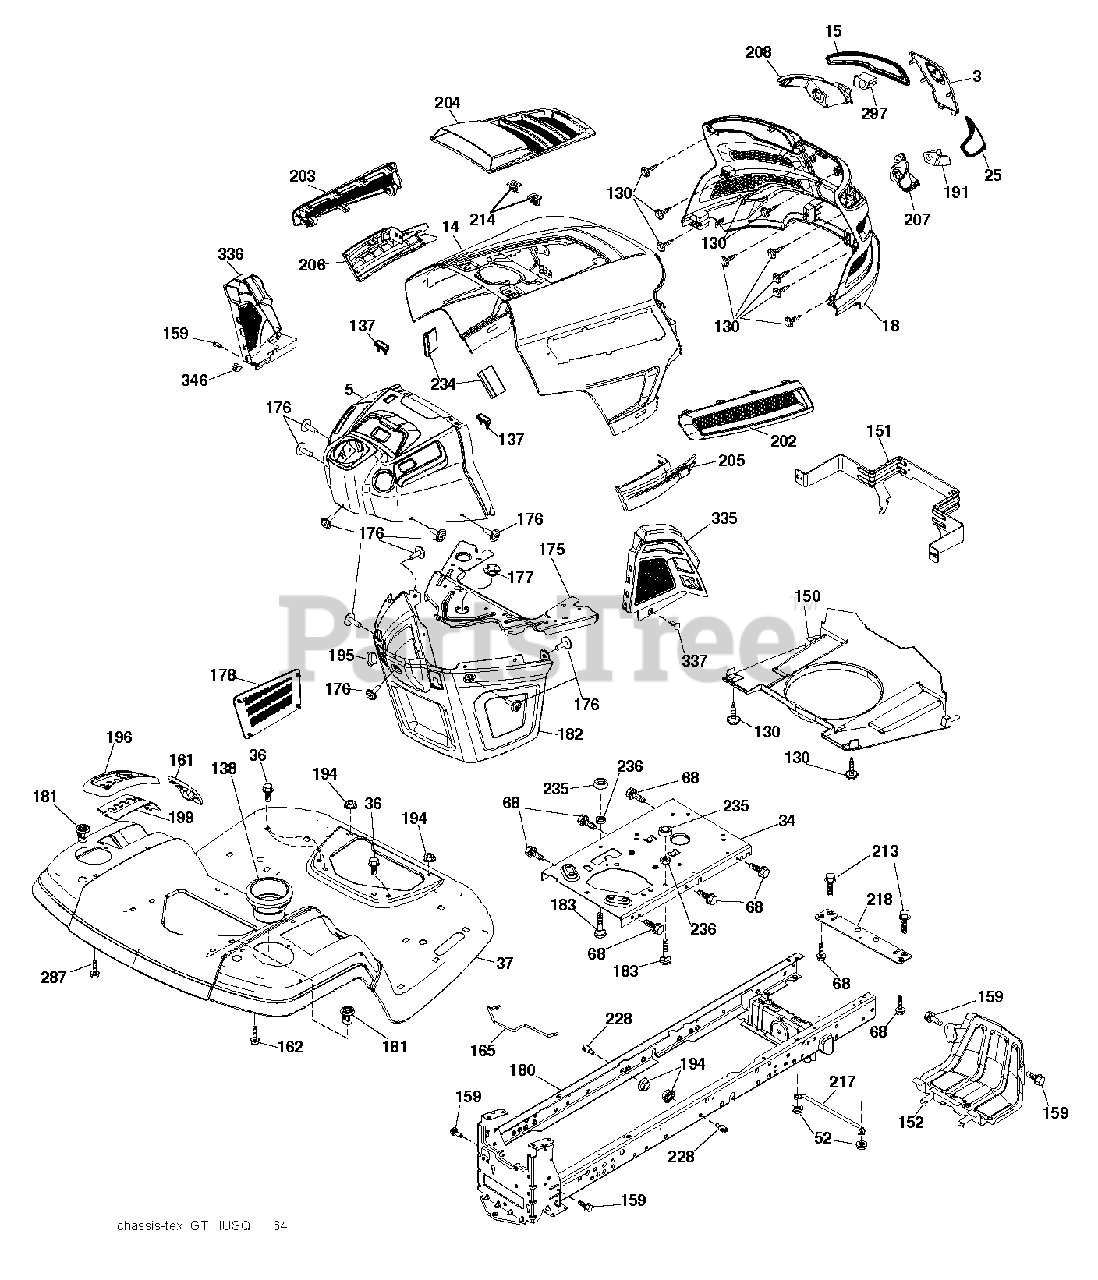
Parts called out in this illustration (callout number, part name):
3	APPLIQUE.SUBASM.GT.HUSQ.II
5	RP.DASH.UPP.GT2.SM.MC.CHOKE
14	HOOD.ASM.HUSQVARNA.GT.TEX.ORAN
15	LENS.HEADLIGHT.LH.GTII.2011
18	GRILLE.SUBASM.GT.HUSQ.II
25	LENS.HEADLIGHT.RH.GTII.2011
34	PLATE.ENGINE.WELDED.CHASSIS
36	SCREW 5/16"
37	FENDER.TLT.W/CPH.W/FW.ORANGE
52	LOCKNUT
68	SCREW LT
130	SCREW.#10 X 0.750.BOS
137	BUMPER DASH
138	HOLDER.CUP.LT.GREY
150	AIR DUCT.GTV2(1.66"RING HEIGHT
151	BRACKET.PIVOT.HOOD.GT.HUSQ.II
152	SHIELD.BROWNING.PNT.GT.V2
159	SCREW, 3/8-16X3/4
161	WINDOW.FUEL.LT.HUSQ.TEX.498
162	SCREW.HI-LO.CONSOLE
165	SUPPORT.TANK.REAR.W/TEX
175	PLATE.CROSSMEMBER.HUSQ
176	SCREW.#10-24X5/8.RN.QU
177	BUSHING, STEERING
178	CARGO.ASM.NET.TXGT.W/C
180	CHASSIS
181	BUSHING.MNT.FEND.CRGO.TEX.49
182	DASH.LOWER.COMMON.12V.ADAPTOR
183	BOLT.5/16-18X1-1/4 FULL THD
191	INSERT.REFLECTIVE.RH.HUSQ.GTII
194	NUT LOCK HEX FLANGE 5/16-18
195	PLUG.HOLE.DASH.LOWER.12V.BLK
196	DECKLFT.CONSOL FULL ASSM GREY
199	PLATE.DECK.LIFT.HUSQ.LT
202	VENT.SIDE.RH.GT.HUSQ.II.
203	VENT.SIDE.LH.GT.HUSQ.II.498
204	VENT.TOP.HUSQ.GT2
205	SIDE.TRIM.RH.GT.HUSQ.II
206	SIDE.TRIM.LH.GT.HUSQ.II.GRAY
207	BEZEL LIGHT.RH.GT.II.MYLAR
208	BEZEL LIGHT.LH.GT.II.MYLAR
213	BOLT
214	CLIP.RETAINER.TINNER.
217	ROD.PIVOT.HOOD
218	X-PIECE.HOOD.STOP.NON/
228	STUD.FASTNER.W/ANTI-ROTATE
234	BUMPER.HOOD.TEX.HUSQVARNA
235	SPACER FENDER
236	NUT.CENTERLOCK.5/16-
287	SCREW 1/4X20
297	INSERT.REFLECTIVE.LH.HUSQ.GTII
335	COVER.RH.CLOSE.OUT.BLACK
336	COVER-LH.LOWER.DASH.GT2.BLACK
337	CLIP.XMAS.TREE.ITW.2622-00
346	CLIP,INSULATOR
